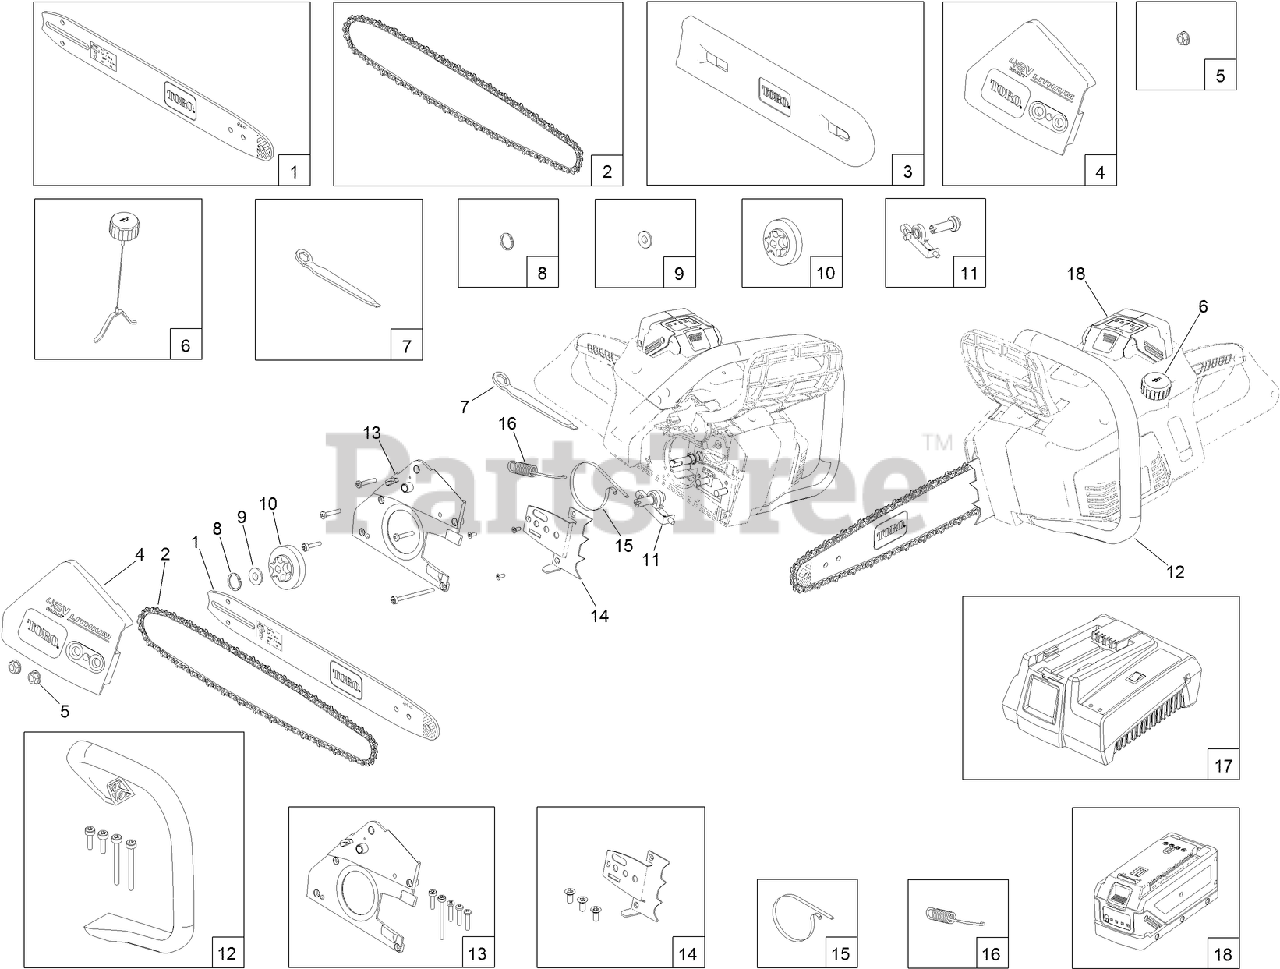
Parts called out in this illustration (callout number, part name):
1	BAR-REPLACEMENT
2	CHAIN-REPLACEMENT
3	SLEEVE-BAR
4	COVER-BAR/CHAIN
5	NUT-M8
6	OIL CAP ASM
7	WRENCH
8	SNAP-RING
9	SPACER
10	SPROCKET
11	BAR AND CHAIN ADJUSTER ASM
12	HANDLE ASM
13	INTERNAL COVER ASM
14	BUCKING TEETH BRACKET ASM
15	BRAKE-BAN
16	SPRING-LEVER, BRAKE
17	CHARGER-REPLACEMENT, 48V
18	BATTERY-REPLACEMENT, 48V
